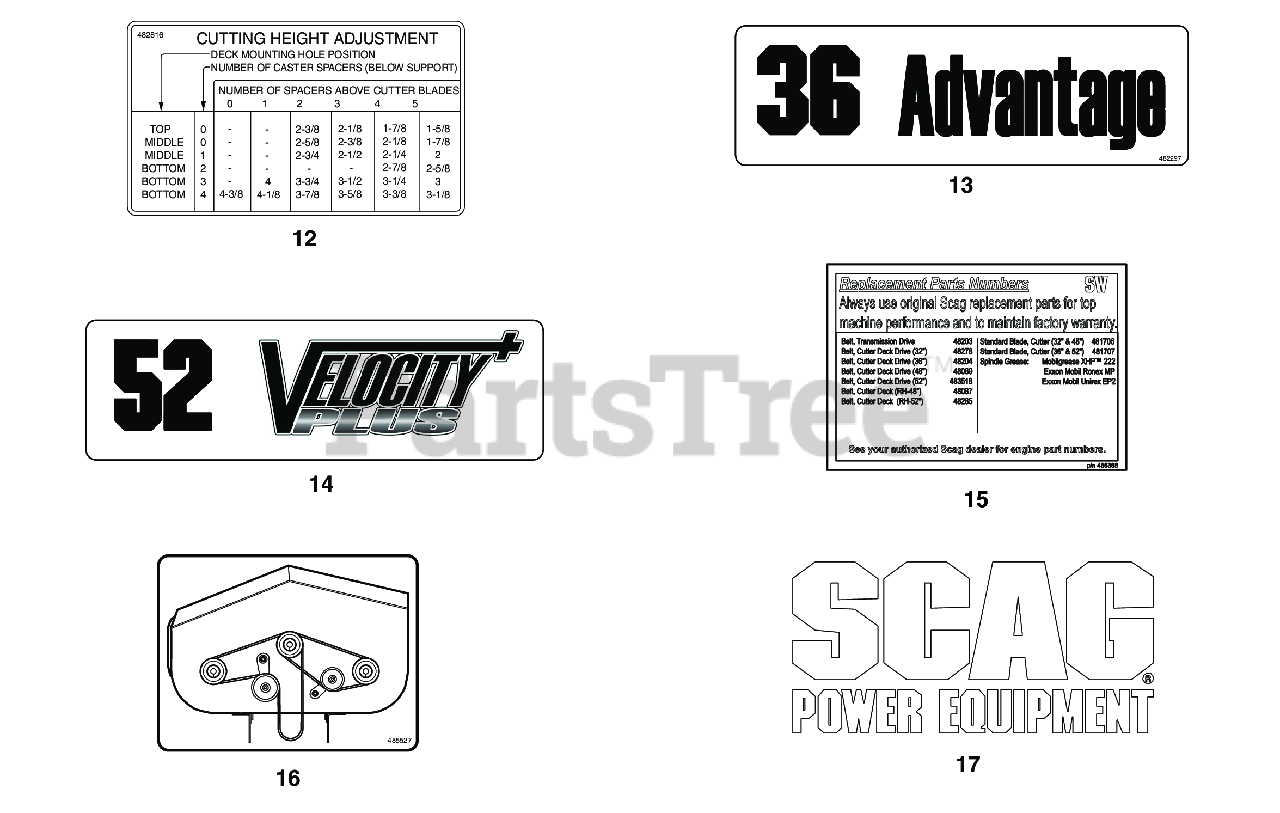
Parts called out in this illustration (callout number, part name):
12	DECAL, HEIGHT OF CUT - SWM
13	Decal, 32
14	DECAL, VELOCITY PLUS - 48
15	Decal, SW Replacement Parts
16	Decal, Belt Routing - 32 & 36A
16	Decal, Belt Routing - 48V, 52V & 61V
17	Decal, Scag Power Equipment (Fuel Tank)
